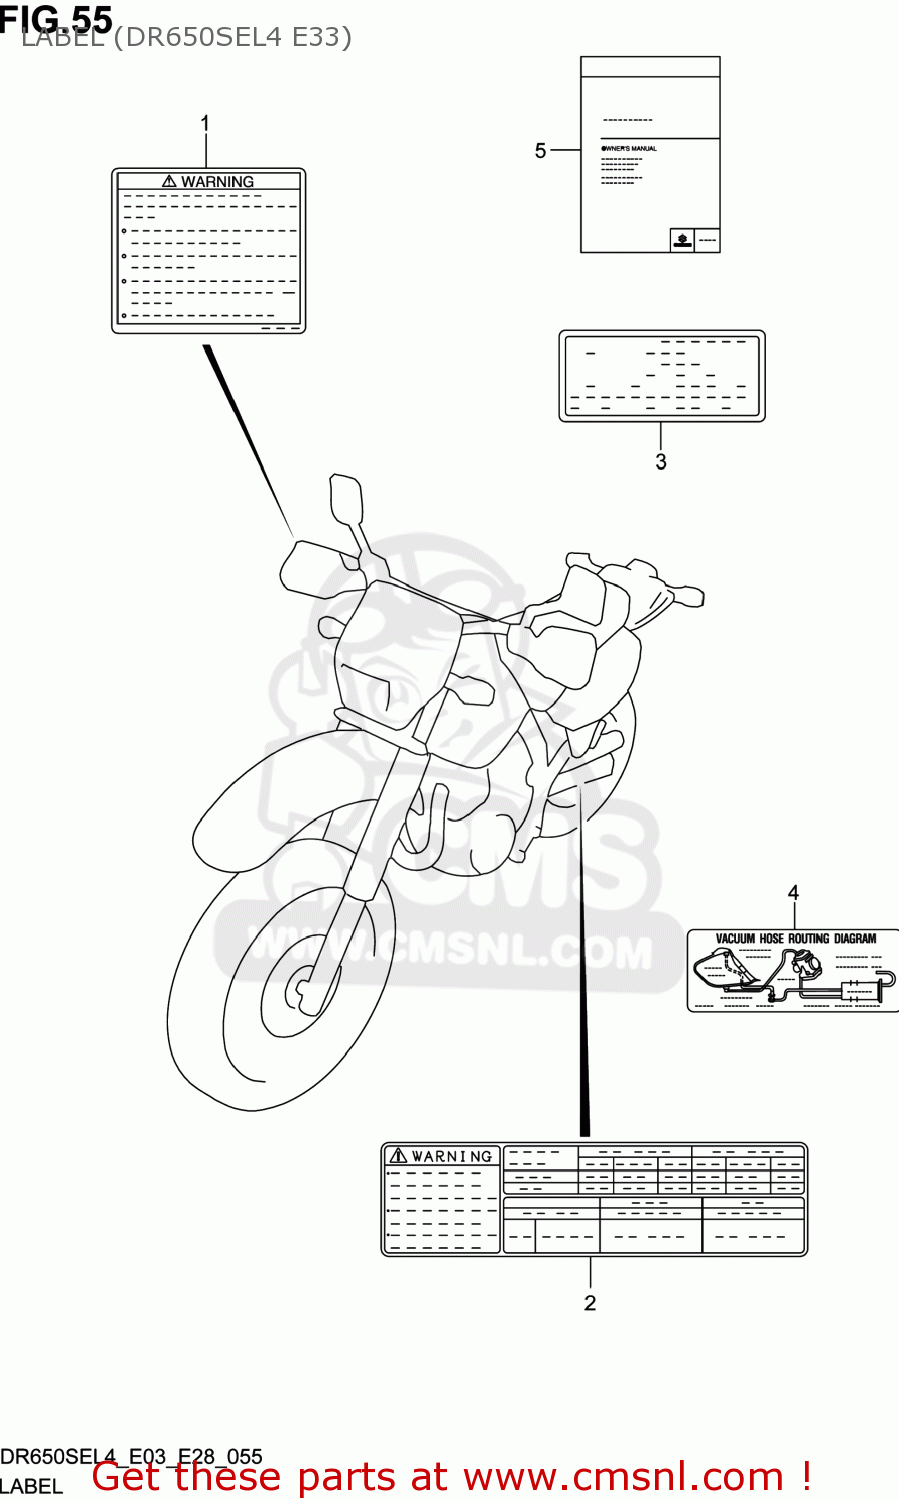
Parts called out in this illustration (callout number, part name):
1	LABEL,GENERAL WARNING
2	LABEL,TIRE INFORMATION
3	LABEL,MANUAL NOTICE
4	LABEL,PIPING DIAG
5	MANUAL,OWNER'S
